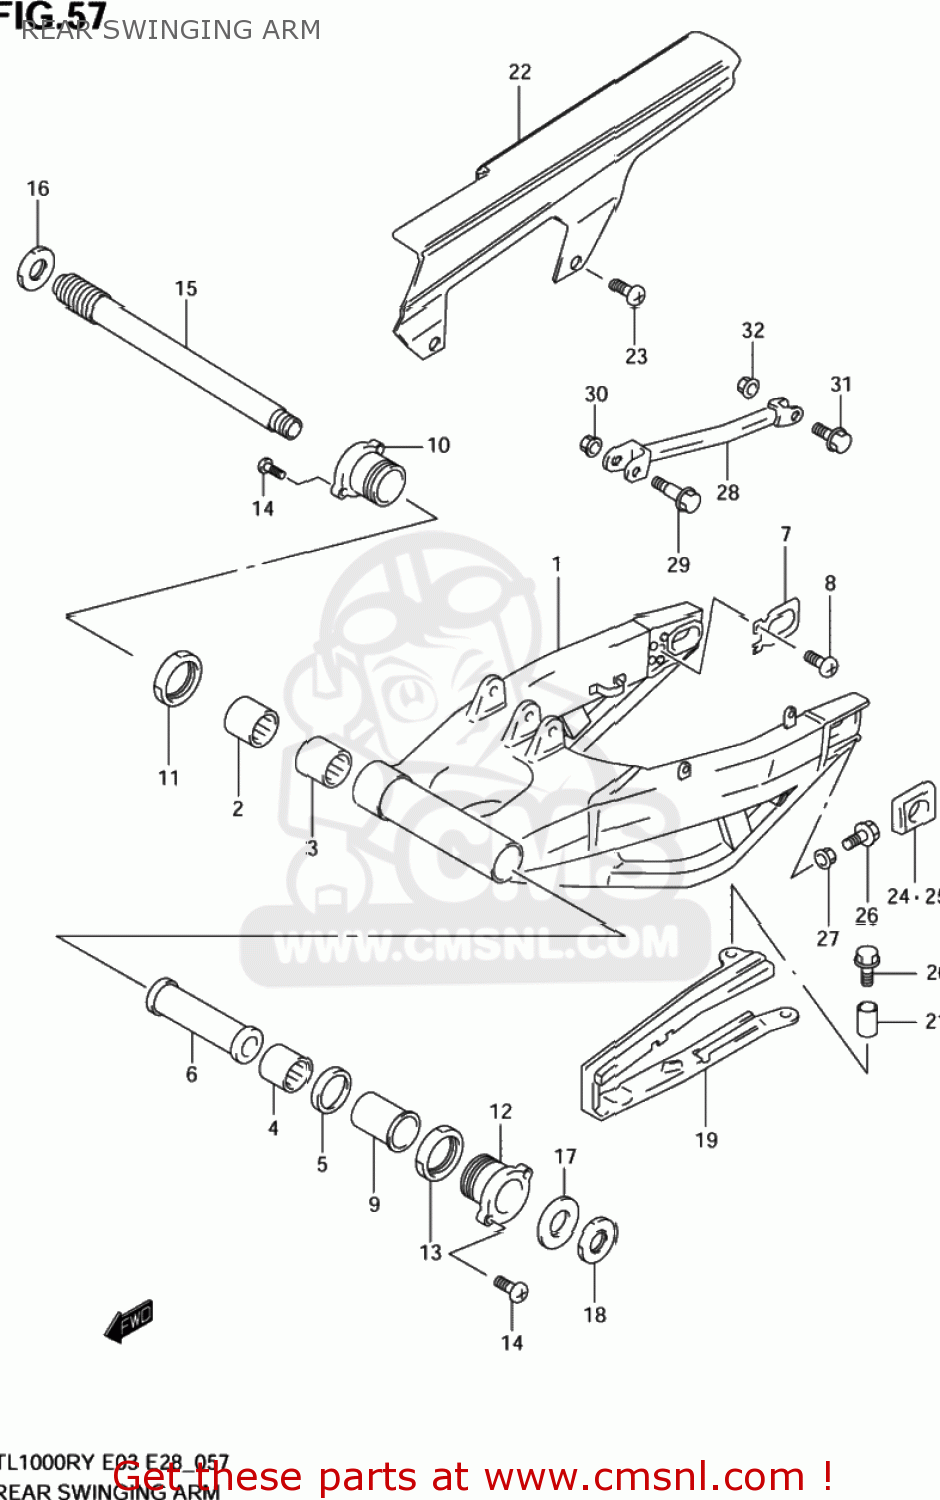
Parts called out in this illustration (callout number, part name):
1	SWINGINGARM ASSY,RR
2	BEARING(25X52X15)
3	BEARING
4	BEARING(30X40X25)
5	SEAL,OIL(30X40X6)
6	SPACER,REAR SWING PIVOT,CENTER
7	PLATE,RR SWING ARM BRKT
8	SCREW
9	SPACER,SWINGINGARM PIVOT BRG
10	BOSS,RR SWINGINGARM PIVOT,R
11	NUT,RR SWGARM PIVOT BOSS,R
12	BOSS,RR SWINGINGARM PIVOT,L
13	NUT,RR SWGARM PIVOT BOSS,L
14	SCREW
15	SHAFT,RR SWINGINGARM PIVOT
16	NUT,RR SWGARM PIVOT BOLT
17	WASHER(25.2X42X3.2)
18	NUT
19	BUFFER,CHAIN TOUCH DEFENSE
20	BOLT(6X20)
21	SPACER(6.5X9X5)
22	CASE,CHAIN
23	SCREW(6X16)
24	ADJUSTER,CHAIN,R
25	ADJUSTER,CHAIN,L
26	BOLT(8X50)
27	NUT
28	TORQUELINK,RR
29	BOLT(8X35.5)
30	NUT
31	BOLT(10X37)
32	NUT
